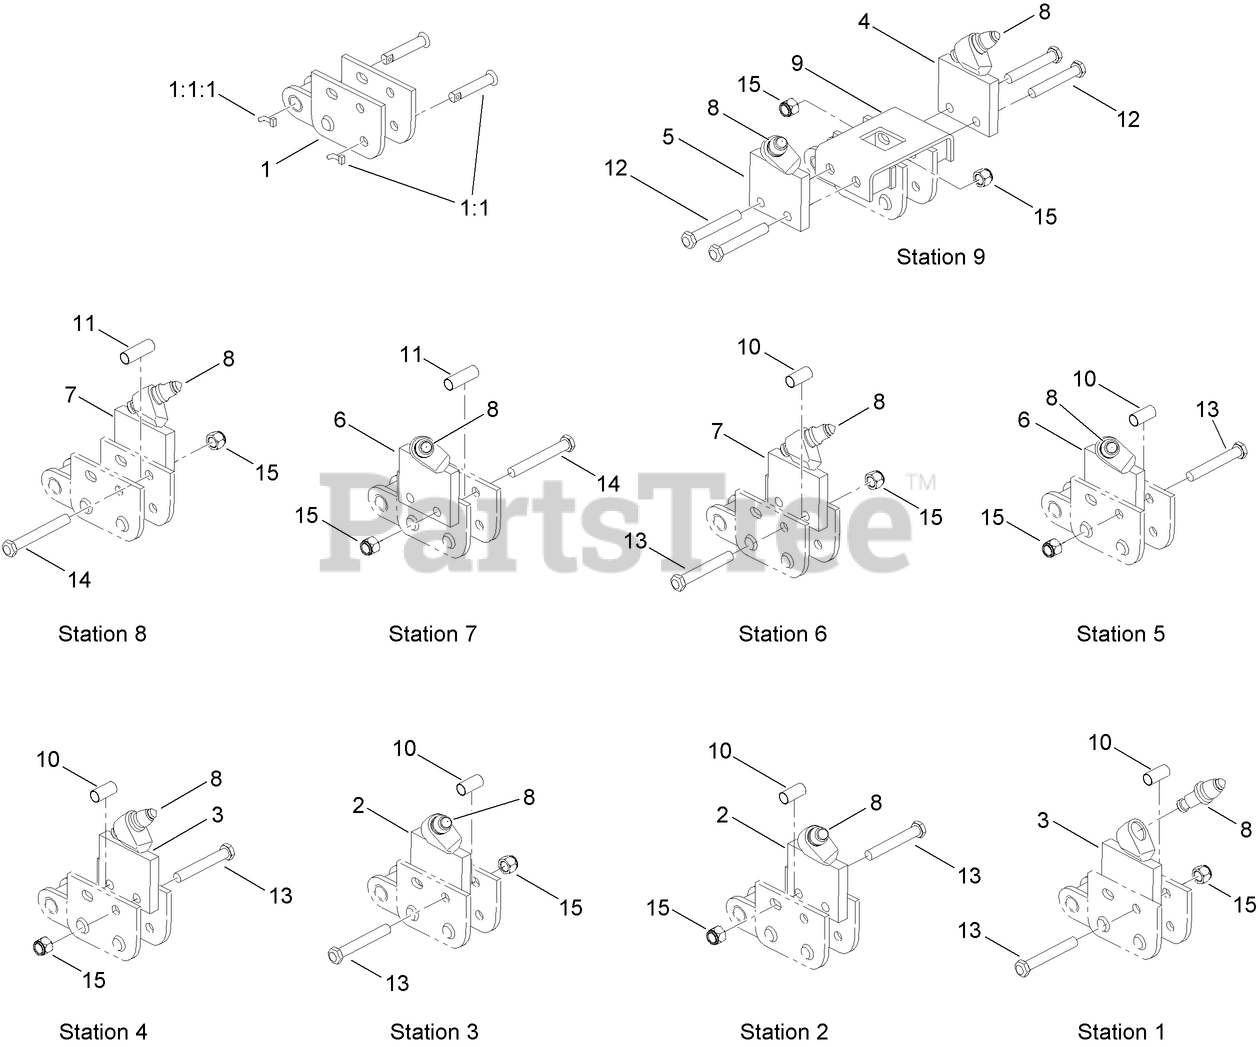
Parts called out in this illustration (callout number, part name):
1	CHAIN REPAIR LINK ASM
1:1	NOTCHED PIN AND KEEPER ASM
1:1:1	PIN-KEEPER
2	HOLDER-BIT, RH CENTER
3	HOLDER-BIT, LH CENTER
4	HOLDER-BIT, RH
5	HOLDER-BIT, LH
6	HOLDER-BIT, RH
7	HOLDER-BIT, LH
8	BIT-CARBIDE, FULL CAB
9	SADDLE-TOOTH SPREADER
10	SPACER-TUBE, INSIDE ADAPTER
11	SPACER-TUBE, OUTSIDE MOUNT
12	BOLT-HH
13	BOLT-HH
14	BOLT-HH
15	NUT-LOCK
